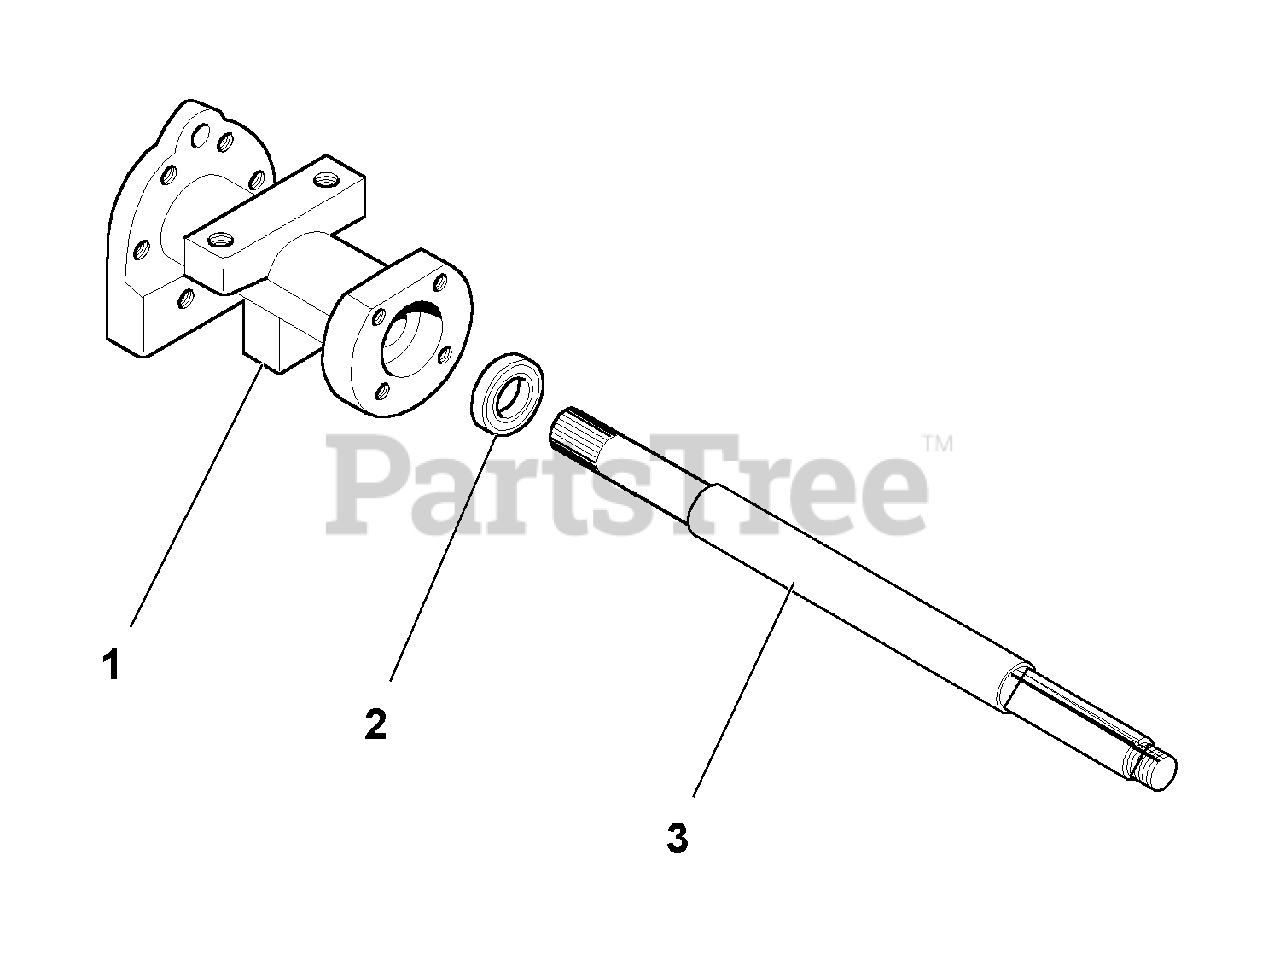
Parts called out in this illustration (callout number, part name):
1	HOUSING, Axle, 8-3/8" Long
2	BEARING, Ball
3	AXLE, 16-9/16"Long
